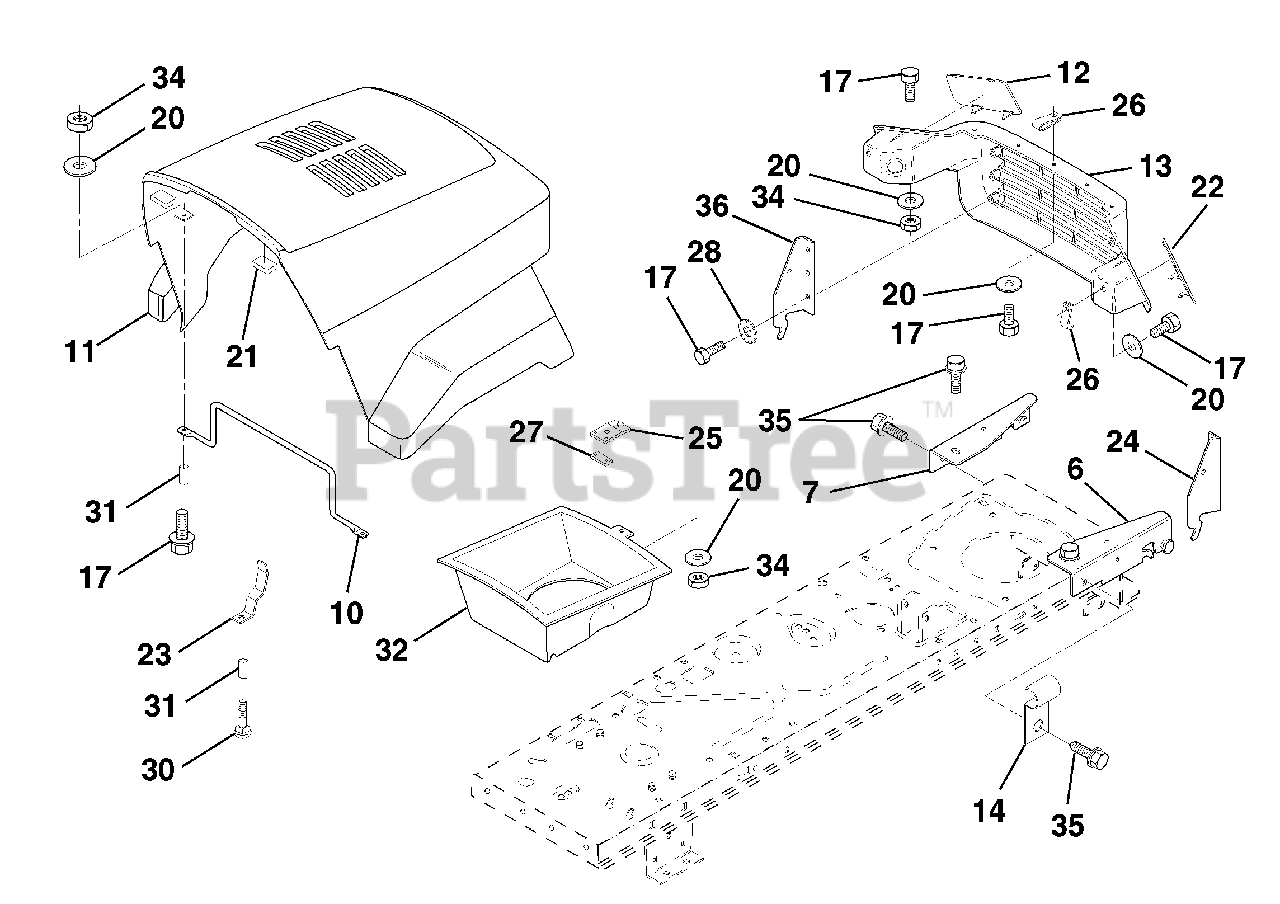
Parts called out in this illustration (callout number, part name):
3	Bracket Pivot Hood LH
6	Bracket Asm. Pivot Hood RH
7	Bracket Asm. Pivot Hood LH
10	Brace Hood
13	Grille
14	Clip Line Fuel
17	Bolt Fin Hex 1/4-20 x 5/8
20	Washer Flat 1/4
21	Bumper Hood
23	Latch Hood
24	Bracket Pivot Hood RH
25	Clip, Duct Air
26	Clip, Tinnerman
27	Clip, Tinnerman
28	Washer Lock Ext Tooth
30	Bolt Rdhd. Sht. Nk 1/4-20 x 1-3/8
32	Duct Air Hood
33	Bolt Hex Fin 1/4-20 x 1-1/2
34	Nut Crownlock 1/4-20
35	Screw Thdrol 5/16-18 x 3/4
